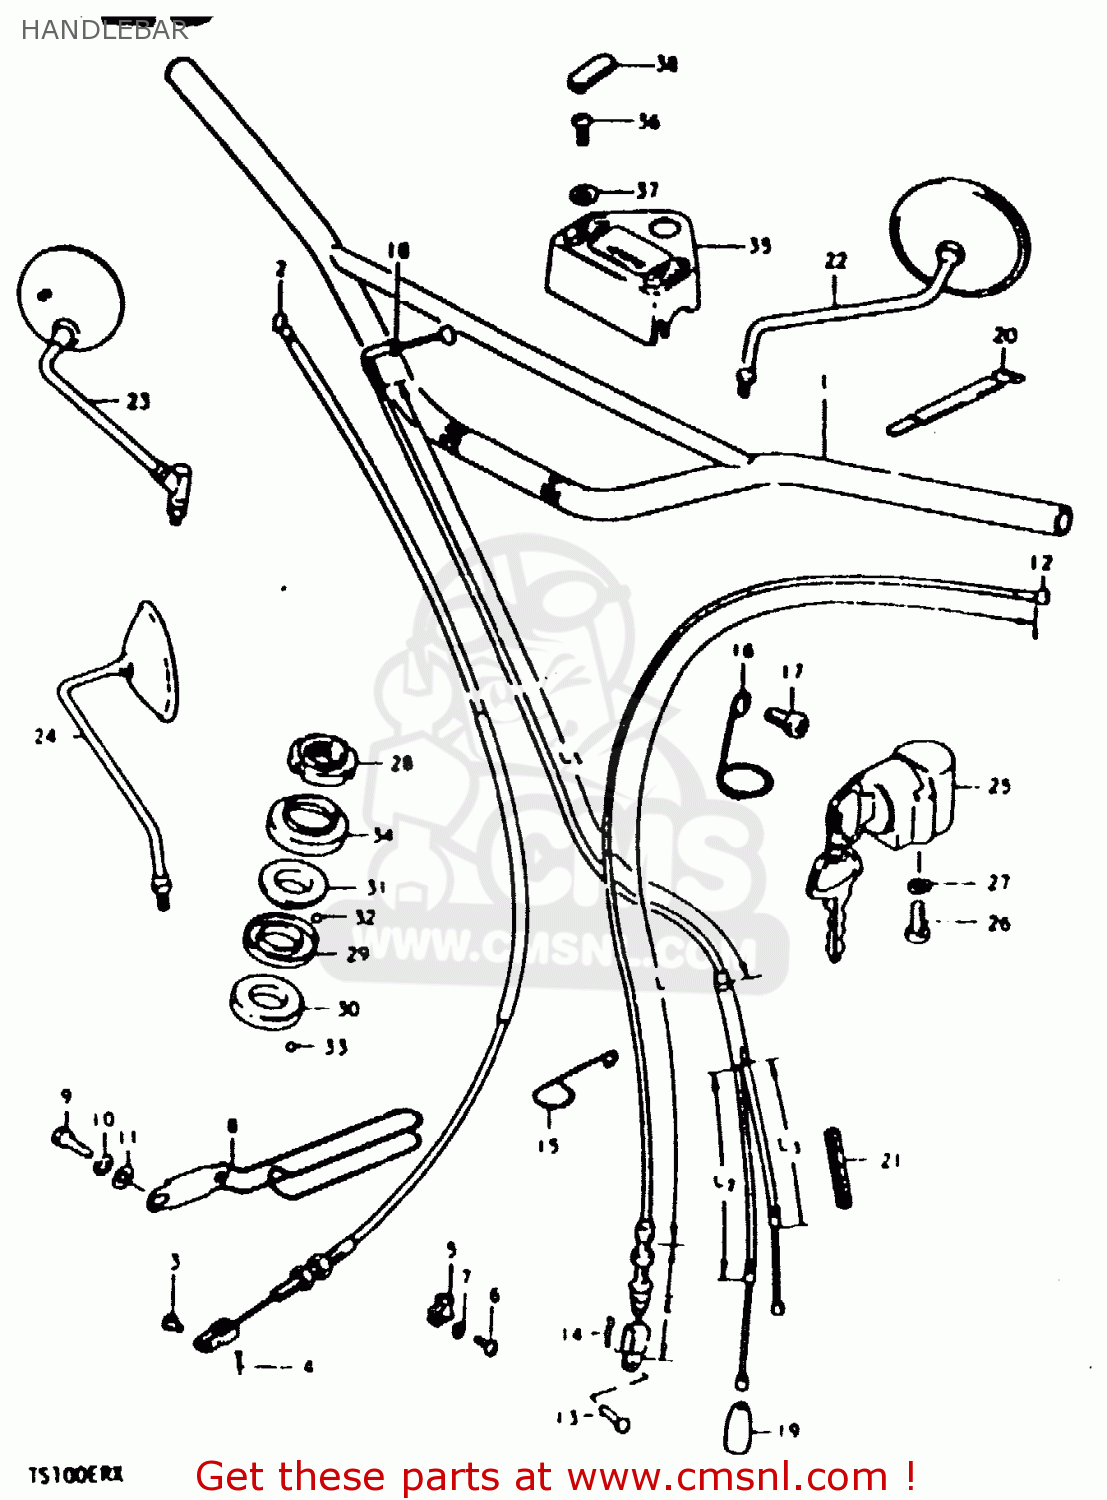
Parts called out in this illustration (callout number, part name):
1	HANDLEBAR
2	CABLE ASSEMBLY,FRONT BRAKE
3	PIN(L:13.5)
4	PIN
5	GUIDE,CABLE
6	SCREW
7	LOCK WASHER
8	GUIDE,CABLE
9	BOLT 8X12
10	LOCK WASHER
11	WASHER
12	CABLE ASSEMBLY,CLUTCH
13	PIN(L:15)
14	PIN
15	CLAMP
16	CLIP
17	SCREW
18	CABLE ASSEMBLY,THROTTLE
19	SEAL,DUST(7X18X30)
20	CLAMP
21	PROTECTOR,CABLE
23	MIRROR ASSY,RH
25	LOCK ASSEMBLY,STEERING
26	SCREW
27	LOCK WASHER
28	NUT, STEERING STEM
29	RACE,STEERING INNER UPR
30	LACE,STEERING INNER LWR
31	RACE,STEERING OUTER UPR
32	BALL
33	BALL
34	DUST SEAL,STEERING UPR
35	COVER,STEERING HEAD
36	SCREW 6X12
37	WASHER
38	CAP,PILOT BOX BOLT
